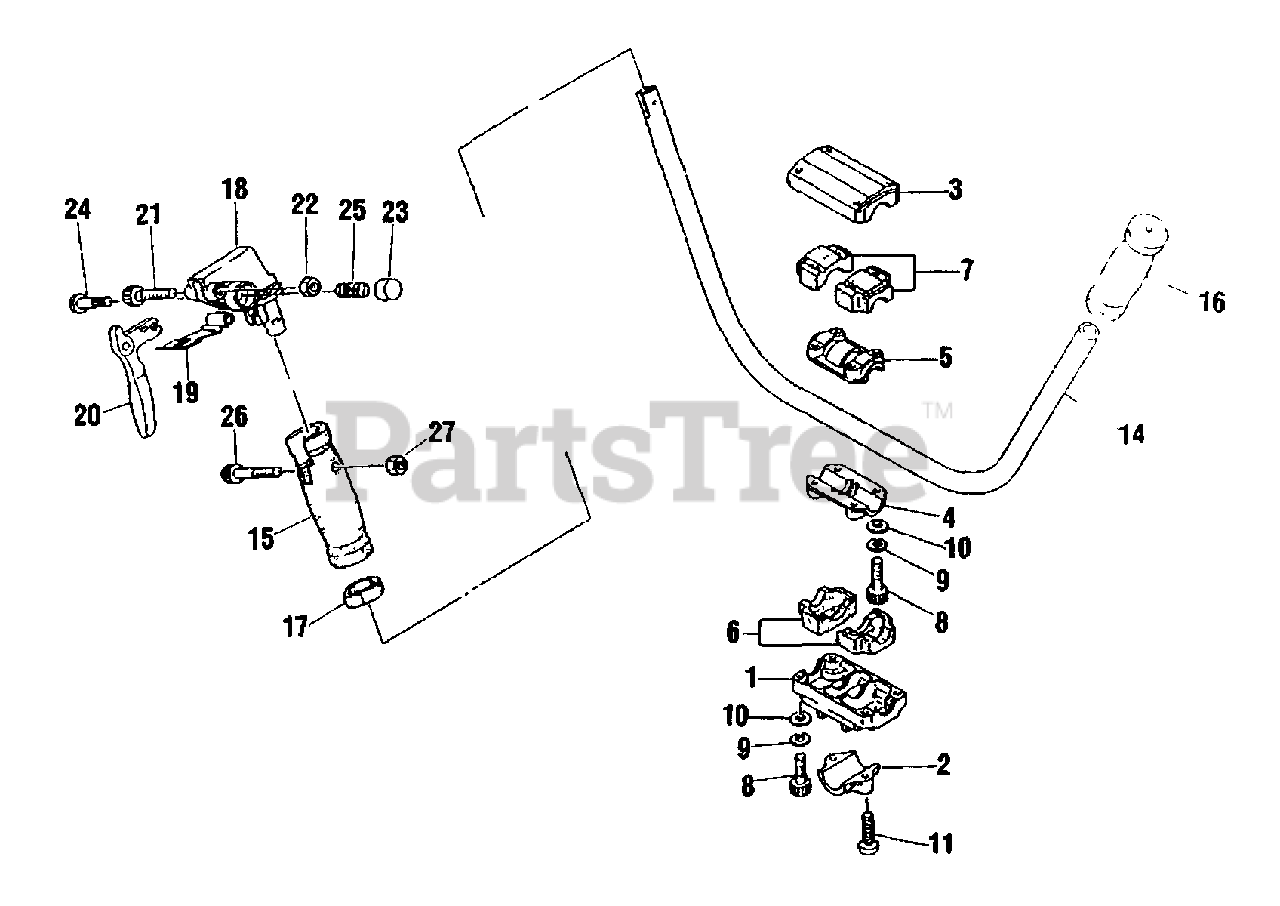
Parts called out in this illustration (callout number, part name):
1	BRACKET, HANDLE
2	SPACER
3	CAP - UPPER
4	CLAMP - LOWER
5	CLAMP - UPPER
6	CUSHION - LOWER
7	CUSHION - UPPER
8	SCREW - 5X25
9	LOCKWASHER - 5
10	WASHER - 5
11	SCREW - 6X28
14	HANDLE
15	GRIP - RIGHT
16	GRIP - LEFT
17	HOLDER, CABLE
18	THROTTLE BODY
19	THROTTLE LEVER STOPPER
20	TRIGGER, THROTTLE
21	BOLT
22	LOCKNUT - 5
23	KNOB, LOCK
24	PIN - LOCKING
25	SPRING, LOCK
26	SCREW - 4X25
27	NUT - 4 -- NYLON
